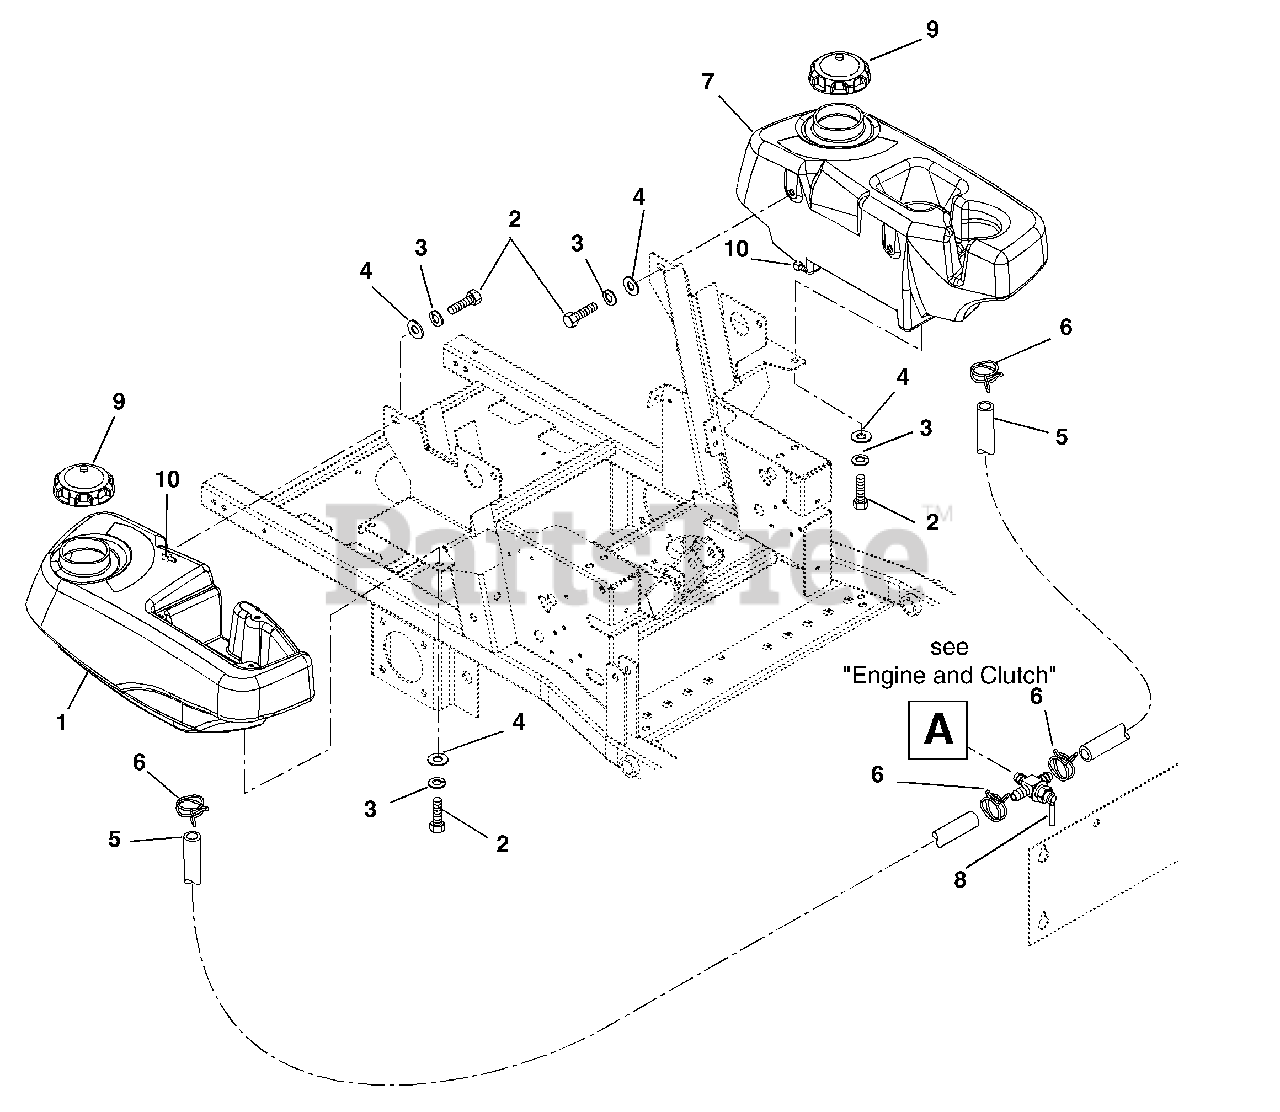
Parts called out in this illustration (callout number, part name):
1	Fuel Tank Right-Hand
2	Bolt-Hex .31-18 x .75 Grade 5
3	Washer-Locking .31 x .078
4	Washer-Flat-Steel .38 x .875 x .083
5	Gas Line-Bulk 1/4" ID
6	Hose-Clamp
7	Fuel Tank Left-Hand
8	Valve-Fuel
9	Cap-Gas
